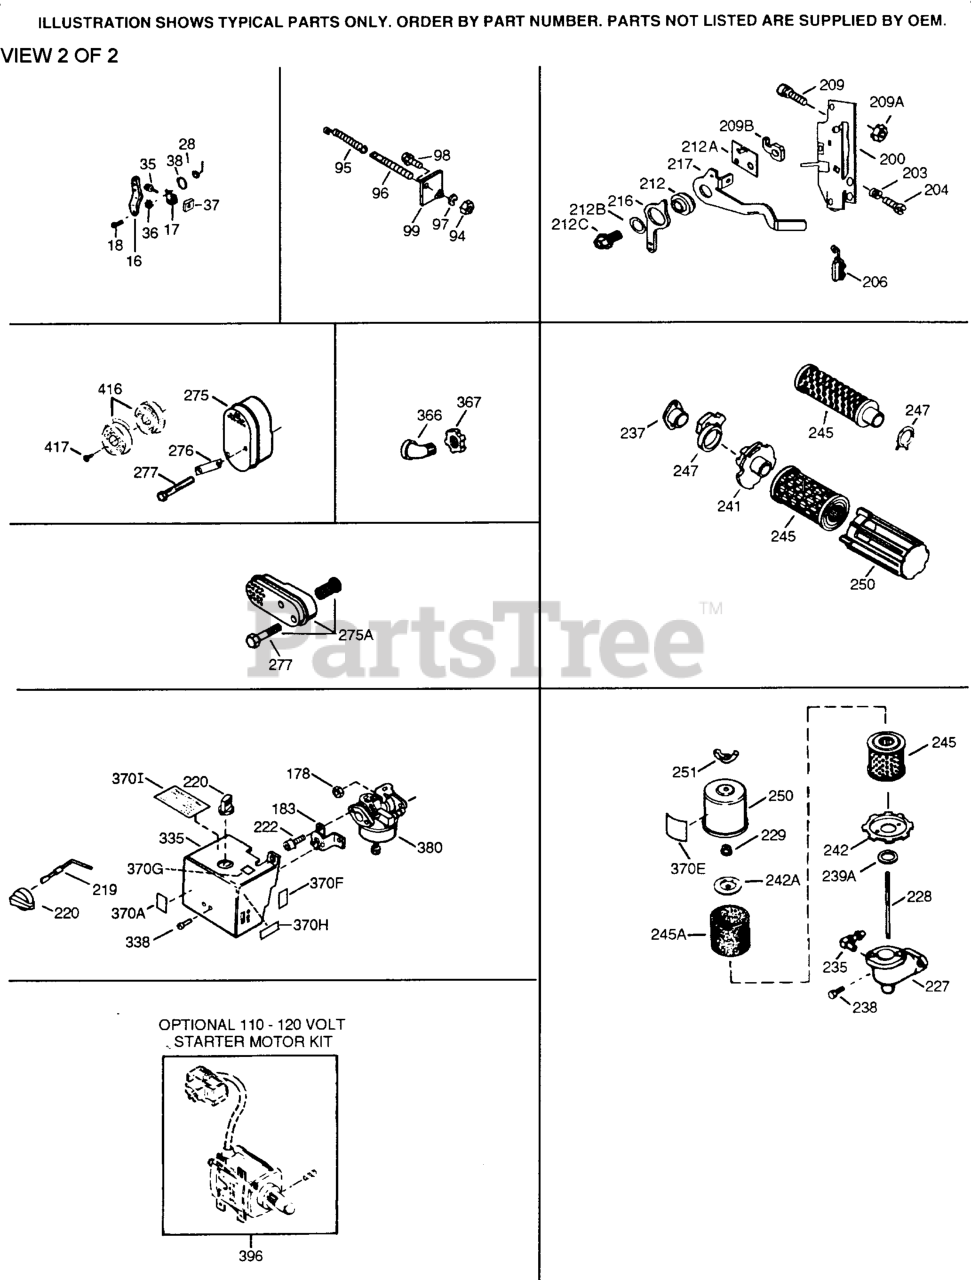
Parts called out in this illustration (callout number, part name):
16	LINK & LEVER
18	SCREW
84	RET RING
183	BRACKET
200	CONTROL ASSY
203	COMP SPRING
204	SCREW
206	TERMINAL
222	SCREW
275	MUFFLER
335	CARB COVER
380	CARBURETOR
395	STARTER KIT
